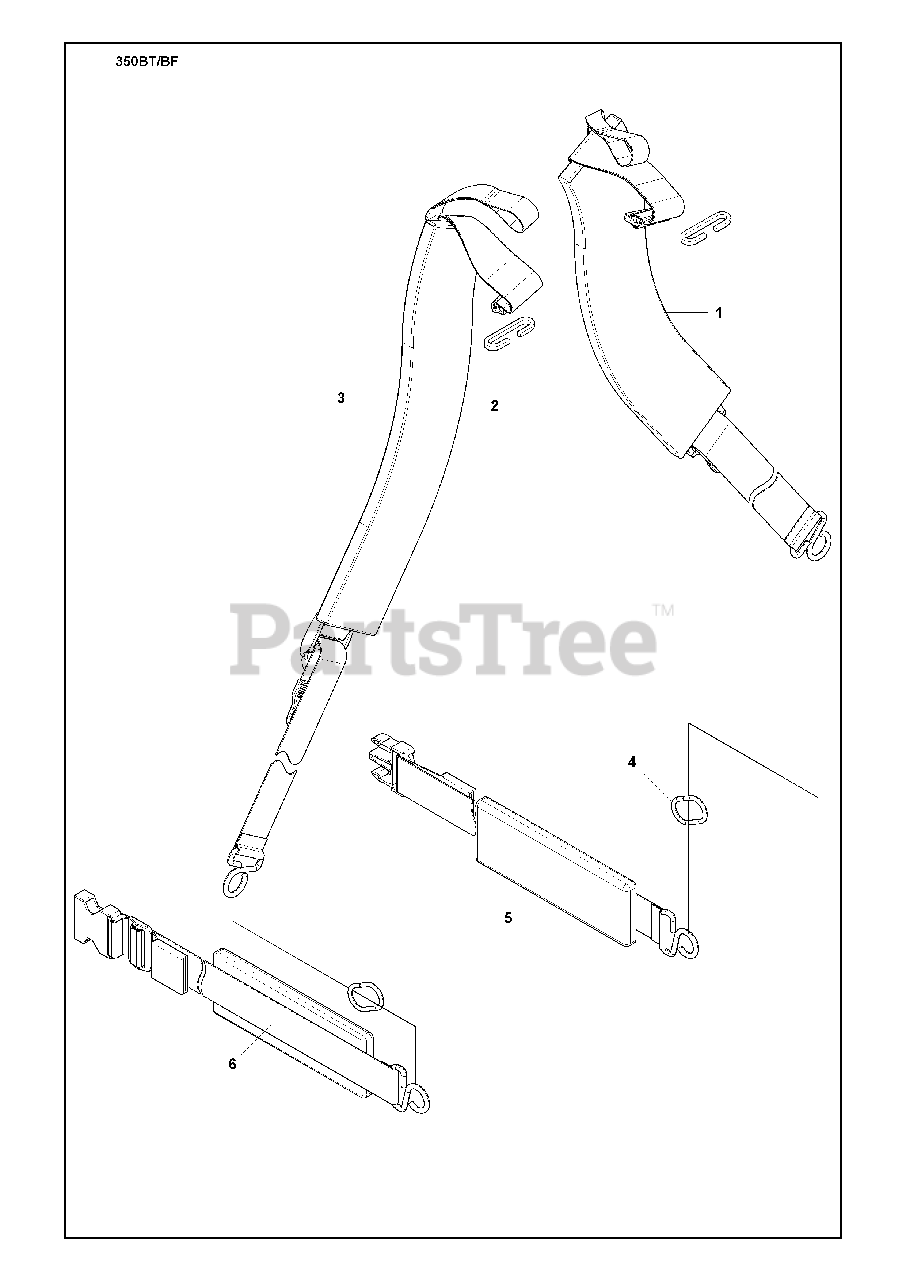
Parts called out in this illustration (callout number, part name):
1	BAND ASSY(R)
3	RP BAND ASSY (L)
4	RING
5	BAND B(R)
6	BAND B(L)
